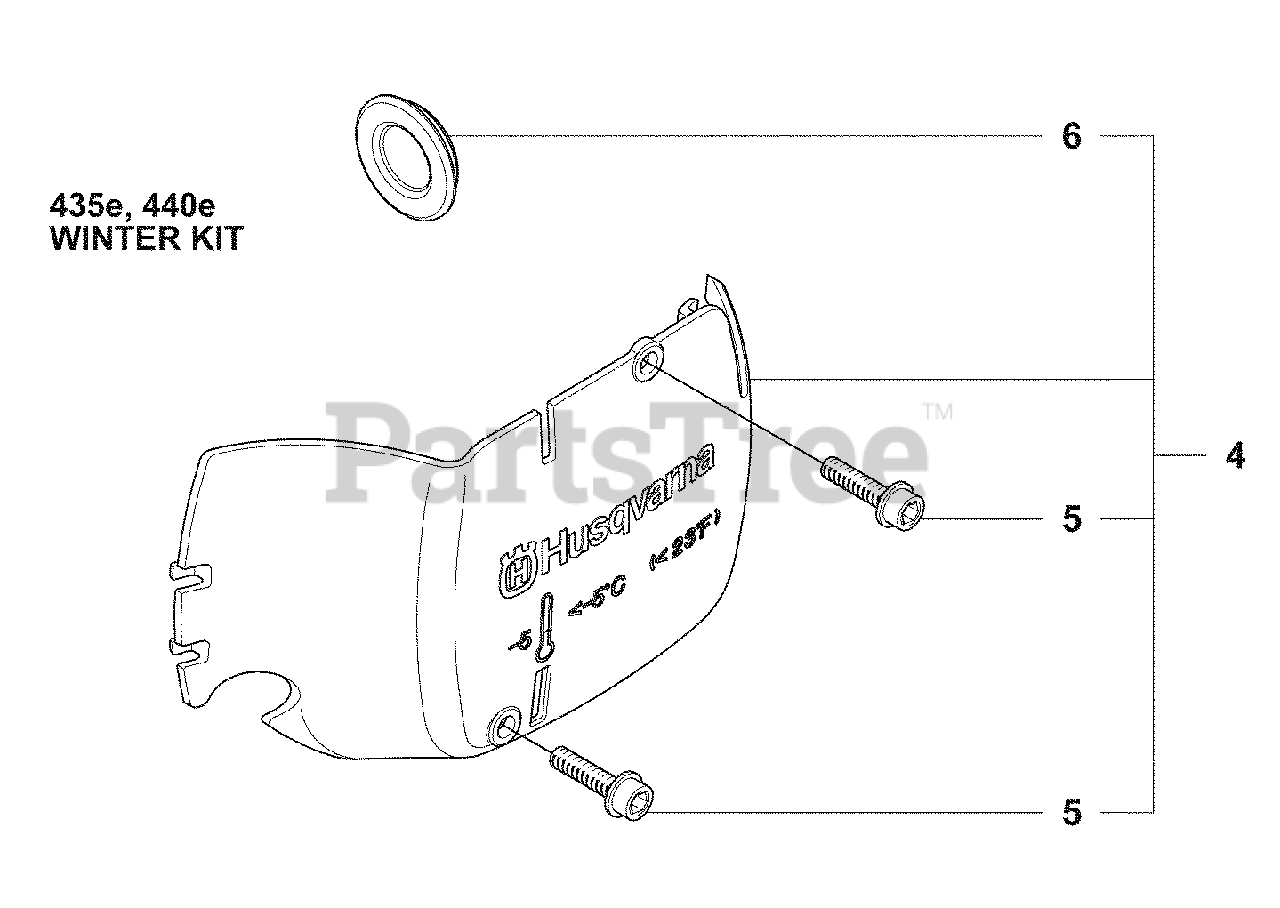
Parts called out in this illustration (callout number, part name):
4	WINTER KIT
5	Screw
6	Plug
